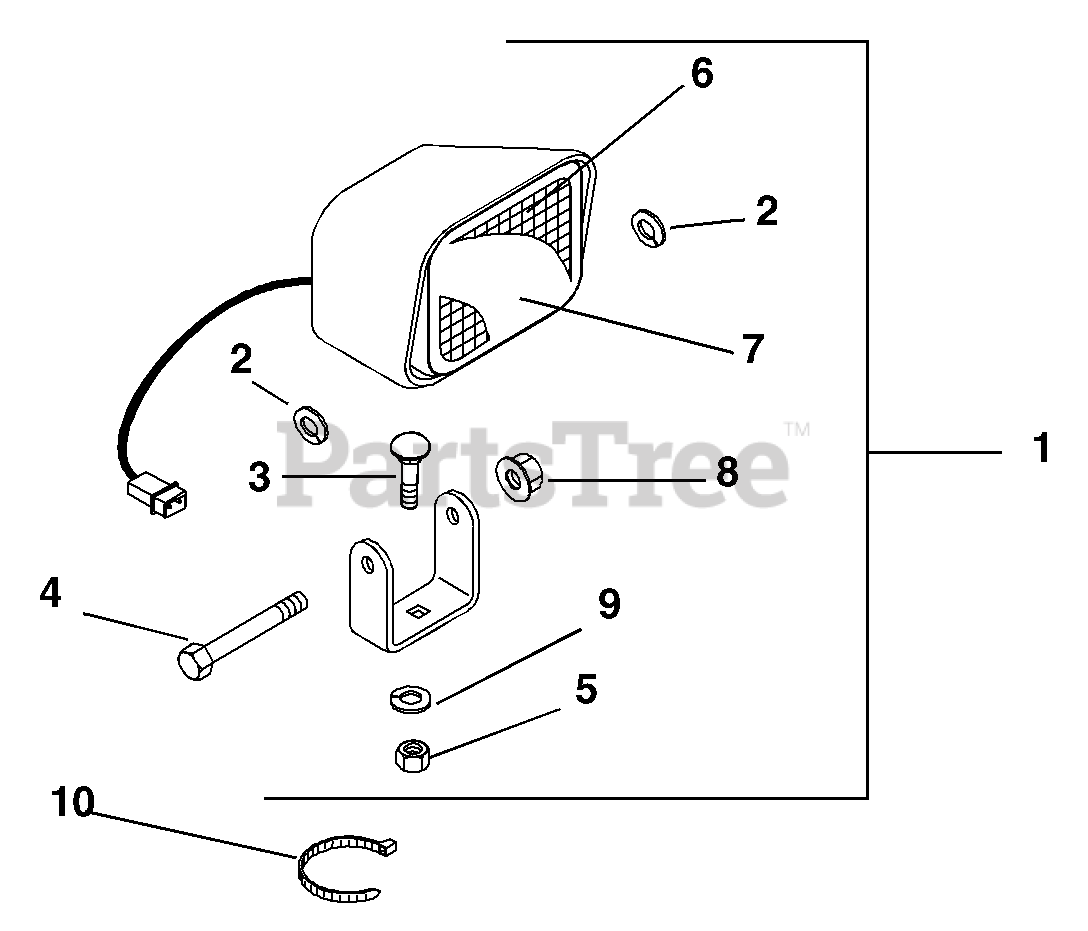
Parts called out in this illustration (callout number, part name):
1	HEADLIGHT
2	@WSHR-LK-EXT.326X.599X.031YWZC
3	@BLT-RDHDSQNK .31-18X1.00 G5YZ
4	@BLT-HEX .31-18X2.50 GR5 YWZC
5	@NUT-HEX .31-18 YWZC
6	LENSE-FLOOD
8	@NUT-SPNLK-FLG .312-18 YWZC
9	WSHR-LK .312X.097 HVY YWZC
10	CABLE TIE LG 5-1/2
